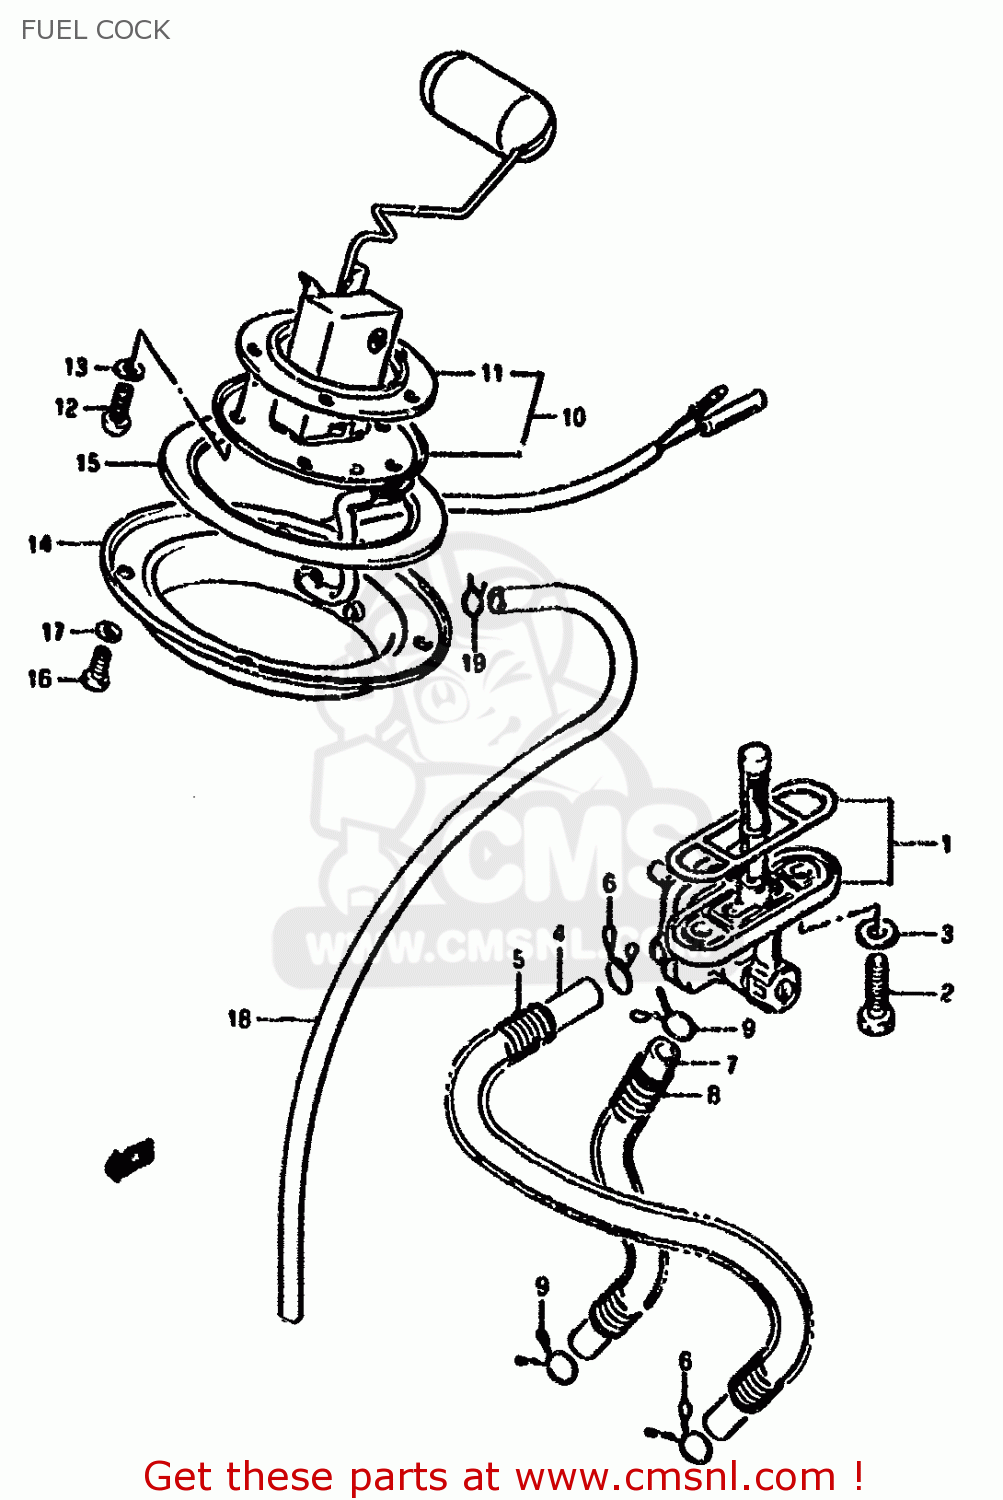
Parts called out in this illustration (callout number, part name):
1	COCK ASSY,FUEL
2	BOLT(6X20)
3	GASKET(5.8X13X1.2) (NAS)
4	HOSE
5	SPRING
6	CLIP
7	HOSE,FUEL NO.3
8	SPRING
9	CLIP
10	GAUGE ASSY,FUEL LEVEL SENDER
11	GASKET,FUEL LEVEL GAUGE (NAS)
12	BOLT
13	LOCK WASHER
14	PLATE,FUEL DRAIN
15	GASKET,FUEL DRAIN PLATE (NAS)
16	SCREW
17	LOCK WASHER
18	HOSE(5X8.2X2000)
19	CLIP
